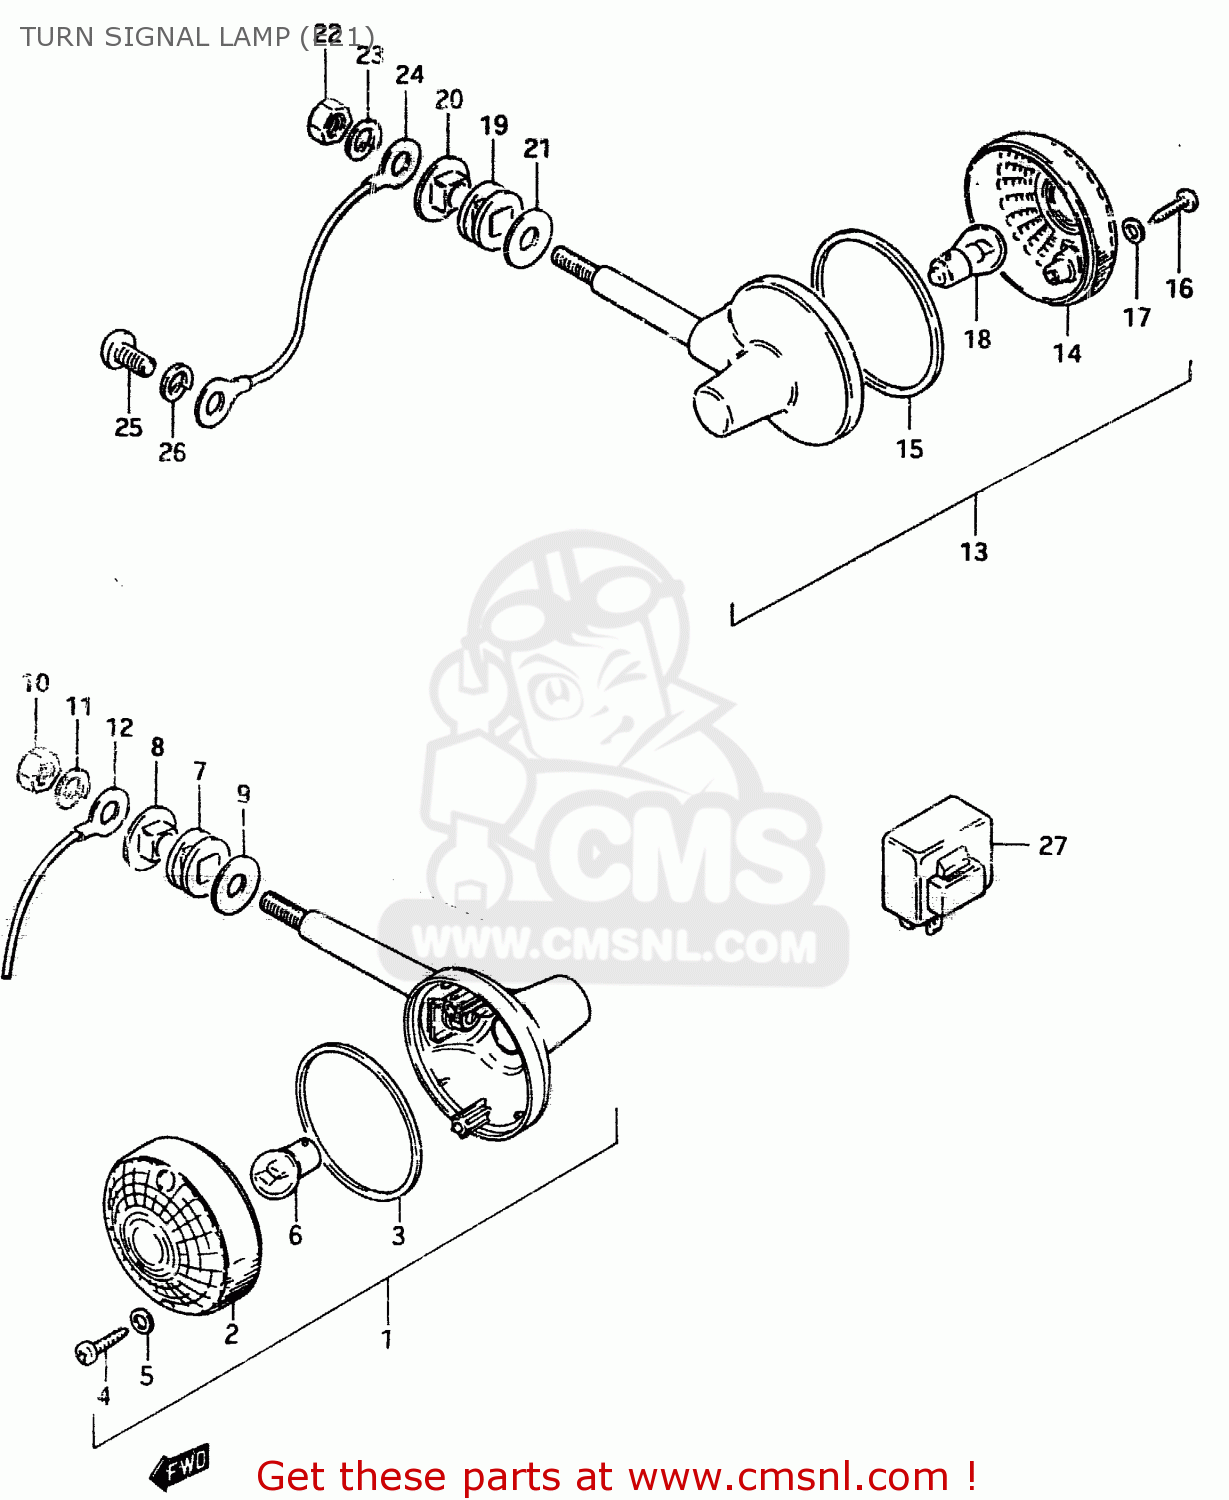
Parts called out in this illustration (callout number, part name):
1	LAMP, FRONT TURN SIGNAL
2	LENS
3	GASKET (NAS)
4	SCREW
5	GASKET (NAS)
6	BULB(6V/10W,STANLEY,A4117)
7	CUSHION
8	SPACER
9	WASHER (10.5X30X2.3)
10	NUT
11	LOCK WASHER
12	WIRE
13	LAMP, REAR TURN SIGNAL
14	LENS
15	GASKET (NAS)
16	SCREW
17	GASKET (NAS)
18	BULB(6V/10W,STANLEY,A4117)
19	CUSHION
20	SPACER
21	WASHER (10.5X30X2.3)
22	NUT
23	LOCK WASHER
24	LEAD WIRE
25	SCREW
26	LOCK WASHER
27	RELAY, TURN SIGNAL
